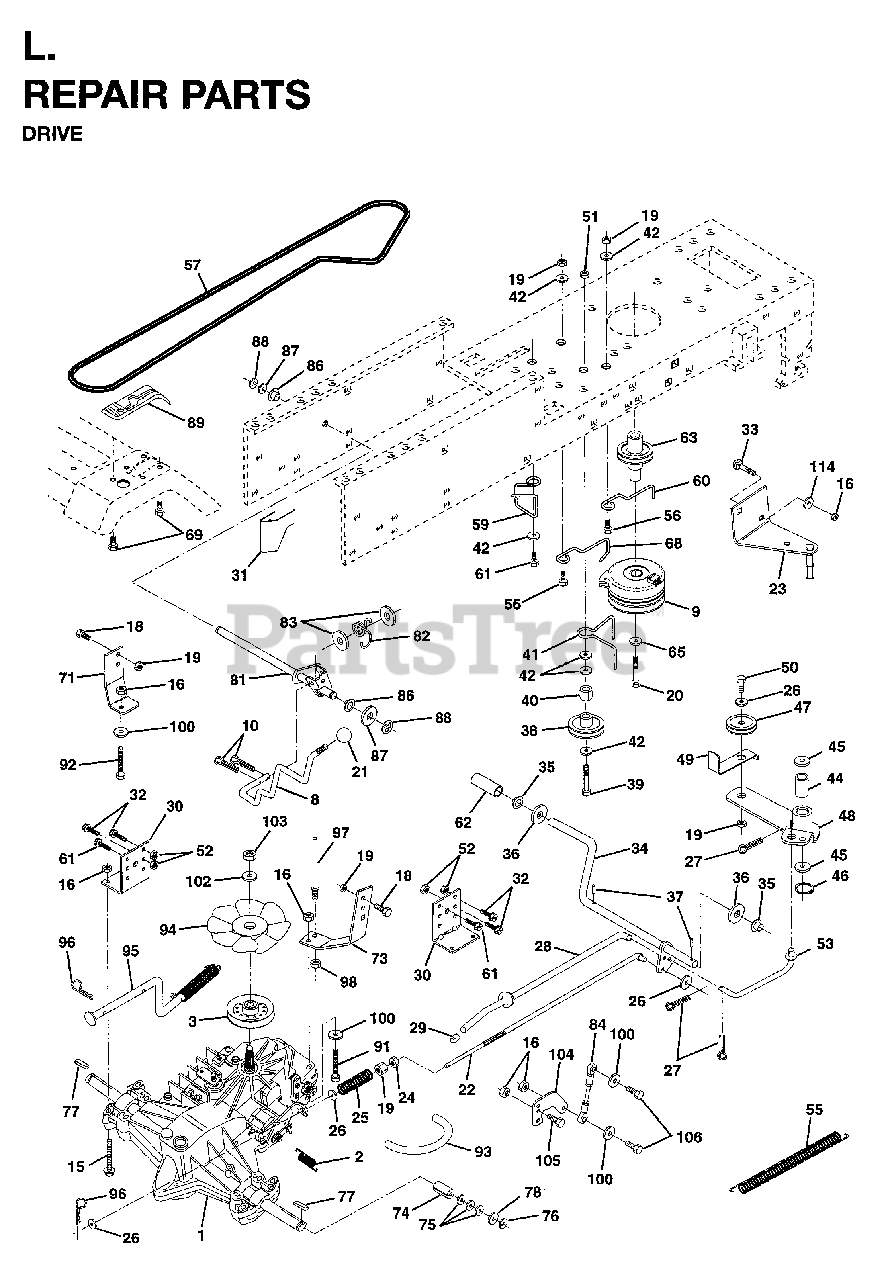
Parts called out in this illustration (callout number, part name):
1	TRANSAXLE ASSEMBLY
2	SPRING BRAKE
3	PULLEY, TRANSAXLE
8	SHIFT ROD
9	CLUTCH ELECT 1051B
10	PIN COTTER
15	BOLT HEX**
16	NUT.71038.31-18.HEX.NYLOCK
19	LOCKNUT
20	BOLT HEX
21	KNOB.DUCKHEAD.1/2
22	ROD BRAKE HYDRO
23	BRACKET, ASM CLUTCH MTG EVX
24	NUT.HEX.3/8-16UNC
25	SPRING ROD LT
26	WASHER
27	COTTER PIN
28	ROD BRAKE PARK LT
29	PLUNGER CAP
30	BRACKET TRANSAXLE
31	KEEPER BELT LH
32	BOLT
33	BOLT
34	SHAFT PEDAL FOOT
35	BEARING.NYLON
37	DRIVE PIN
38	PULLEY.IDLER.FLAT
40	SPACER T
41	BELT KEEPER LT
42	WASHER
44	BEARING LT
45	WASHER LT
46	KLIP RING
47	IDLER PULLEY
48	ARM IDLER
49	RETAIN BELT
50	BOLT
51	LOCKNUT
52	LOCKNUT
53	LINK, CLUTCH LT
55	SPRING, RETURN LT
56	BOLT
57	DRIVE BELT, LTH & YTH TRACTORS
59	KEEPER CENTER SPAN
60	KEEPER BELT ENGLH
62	PEDAL COVER T
63	PULLEY, CLUTCH ELECT EVX
65	LOCKWASHER
68	KEEPER,BLT ENG LT
69	SCREW.HI-LO.CONSOLE
71	STRAP LH TORQUE
73	STRAP RH TORQUE
74	SPACER SPLIT
76	E-RING LT
77	SQUARE KEY
81	SHAFT ASSY
82	SPRING,TORSION
86	BUSHING.STEERING.ROD
88	KLIP RING
89	CONSOLE HYDRO LT
92	HEX BOLT
93	FUEL LINE
94	FAN 7" HYDRO
95	CONTROL ARM, BYPASS HYDRO
96	RETAINER M
97	KEEPER BELT RH
98	NUT.HEX.3/8-16UNC
100	WASHER - 15X7.3X1.6
104	CONTROL ARM
106	BOLT.5/16-18X1-1/4 FULL.THREAD
114	WASHER - 15X7.3X1.6
